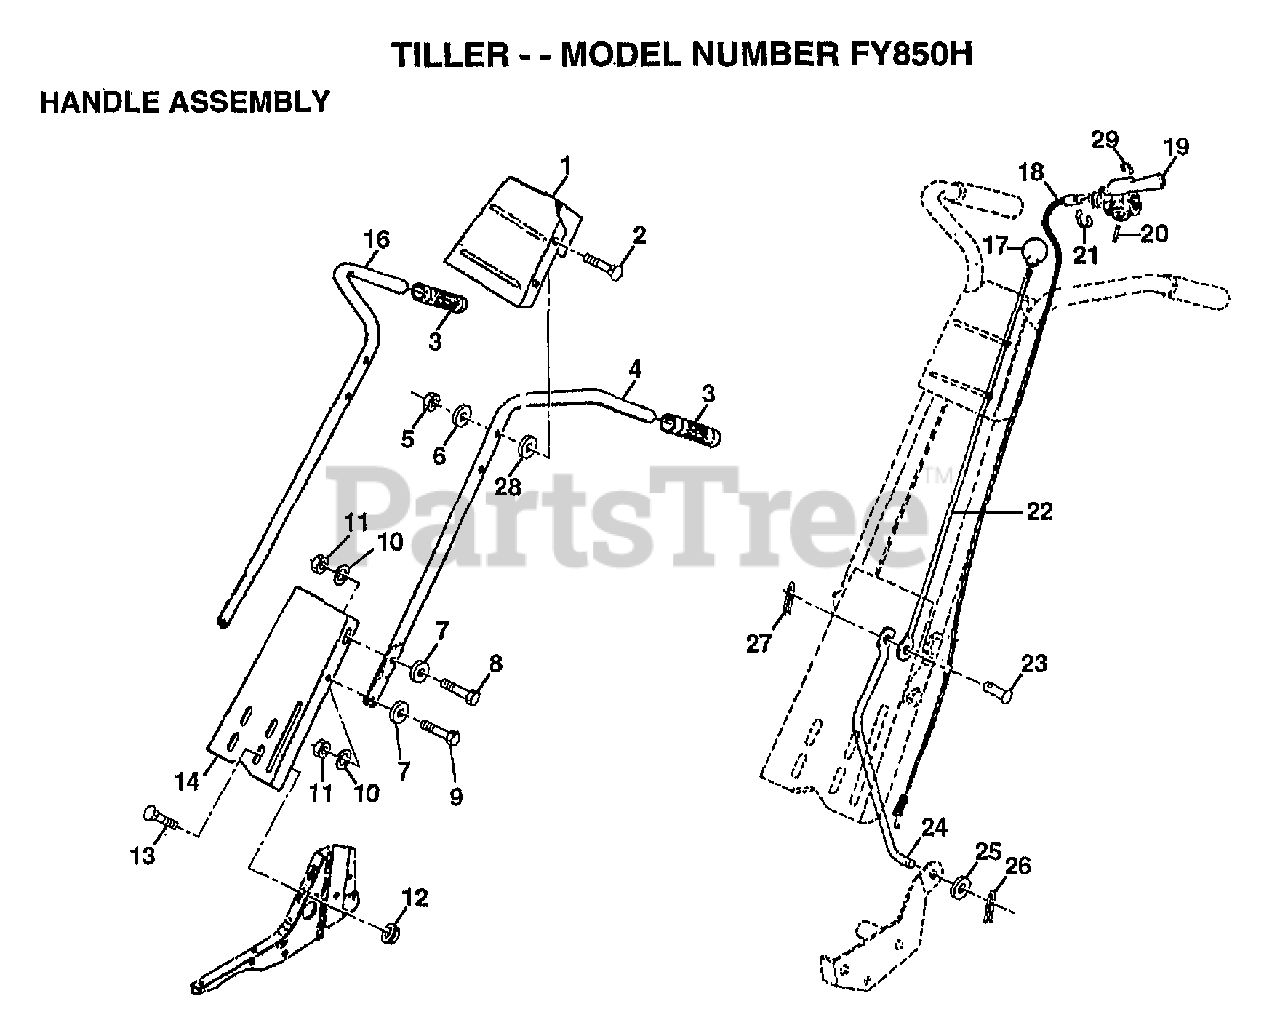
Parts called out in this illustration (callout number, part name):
1	HANDLE BRKT
2	BOLT
4	HANDLE.LH
6	WASHER
7	WASHER
9	BOLT
10	LOCKWASHER
11	NUT.HEX.5/16-18
12	NUT
13	BOLT
17	KNOB T(3/8 HOLE)
18	CABL.CLUTCH.49.88
19	LEVER CONTRL TINE
20	"PIN PIVOT,GROOVED"
21	E-RING
22	ROD.REVERSE.UPPER.22
23	RIVET.RD.HD.DRILL
24	REVERSE ROD TI
25	WASHER
26	COTTER PIN
28	WASHER
29	RETAINER RING
